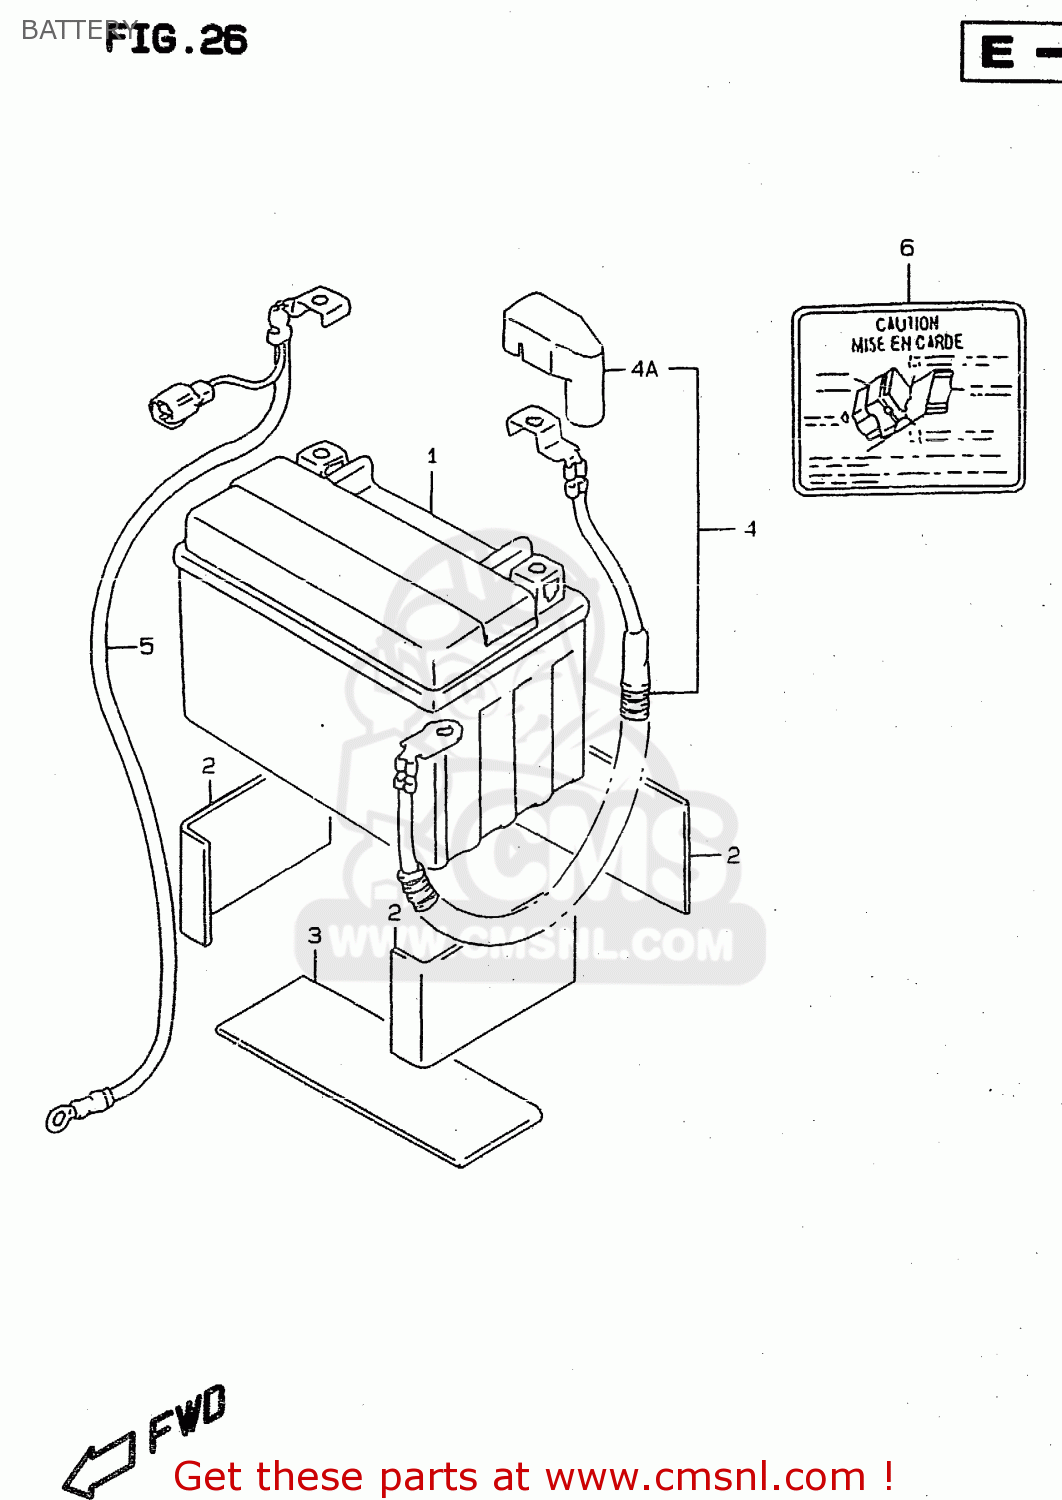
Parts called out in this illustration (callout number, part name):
1	BATTERY ASSY(YTX9-BS,12V8AH)
2	PROTECTOR(170X95X3.0)
3	CUSHION,BATTERY
4	WIRE,BATTERY PLUS LEAD
4A	CAP,BATTERY PLUS
5	WIRE,BATTERY MINUS
6	PLATE,BATTERY CAUTION
